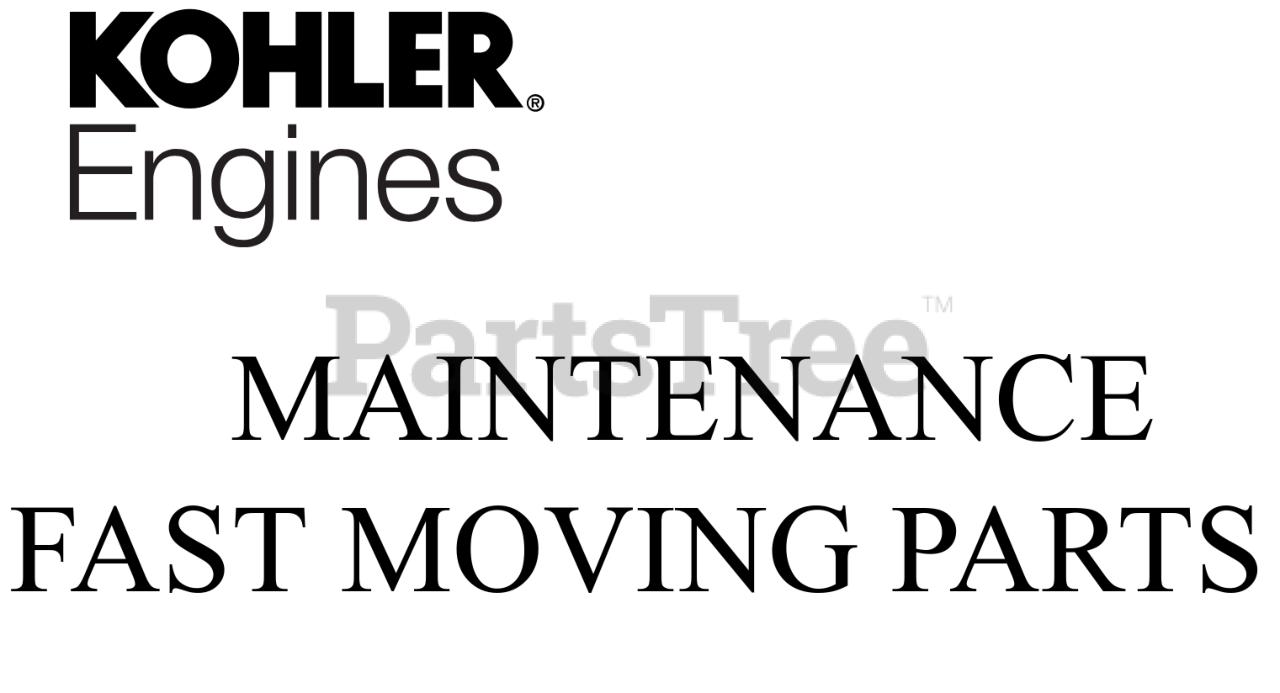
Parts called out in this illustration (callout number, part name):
NI	FILTER, BREATHER
NI	FILTER, FUEL
NI	ELEMENT, AIR FILTER - PRIMARY
NI	ELEMENT, AIR FILTER - SAFETY
NI	PLUG, SPARK (PRO SERIES)
NI	KIT, HDAC MAINTENANCE
NI	OIL FILTER
